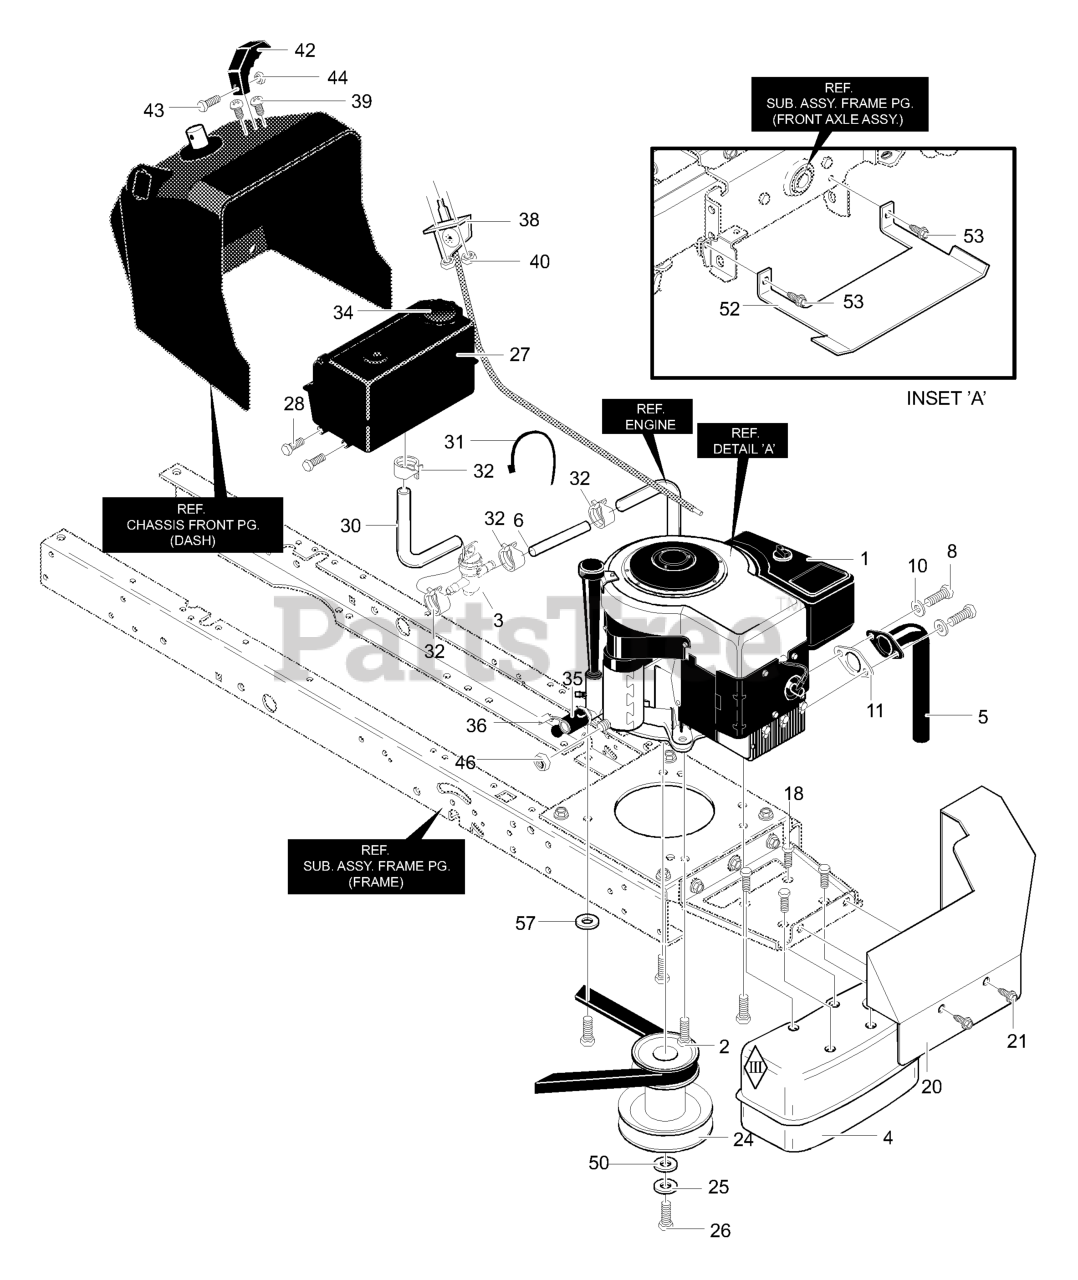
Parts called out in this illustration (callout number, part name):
1	12.5HP Engine
2	Engine Bolt 3/8x1.25
3	Fuel Shut-off Valve
4	Muffler, Super Low
5	Exhaust Pipe
6	Gas Line Tubing 3.250 Inches
8	Screw, 5/16-18 x 0.75
10	Washer, Hvsptlk
11	GASKET, Exhaust
18	Screw, 1/4-20x.63
20	Heat Shield Assembly
21	Screw, 5/16-18 x 0.75
24	Stack Pulley
25	Washer, Regsptlk
26	Screw, 7/16-20
27	Tank, Fuel 1.5 Gal.
28	Screw, 15TPIX
30	Gas line 8 Inches
31	Cable Tie
32	Clamp, Fuel Clamp
34	Gas Cap
35	Oil Drain Valve Assembly
36	Cap, Oil Drain Valve
38	Throttle Control
39	Screw, 10-24x.63
40	Nut, #10-24
42	Knob, Throttle Control
43	Screw, #8-32
44	Nut, #8-32
46	Nut, 1/4-20
50	Flat washer
52	Shield, Anti-Dehydration
53	Screw, 5/16-18 x 0.75
57	Washer, Exlk
